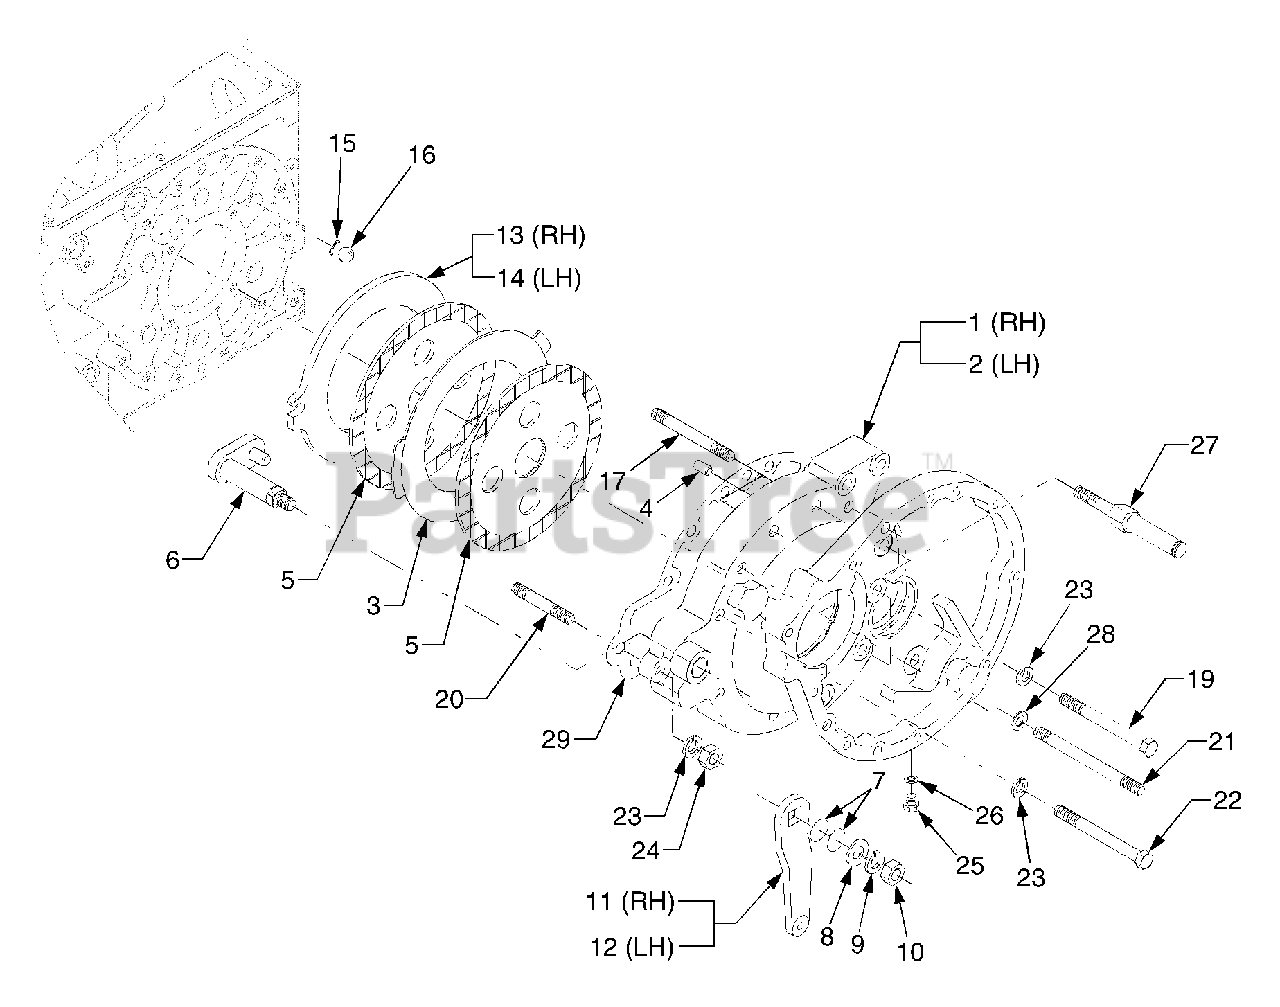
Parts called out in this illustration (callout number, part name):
1	Case, Brake(LH)
2	Case, Brake(RH)
8	Washer, Plain
9	Washer, Spring
11	Lever, Brake Cam(RH)
12	Lever, Brake Cam(LH)
13	Plate, Cam(RH)
14	Plate, Cam(LH)
23	Washer, Spring
27	Shaft, Lever (Range)
